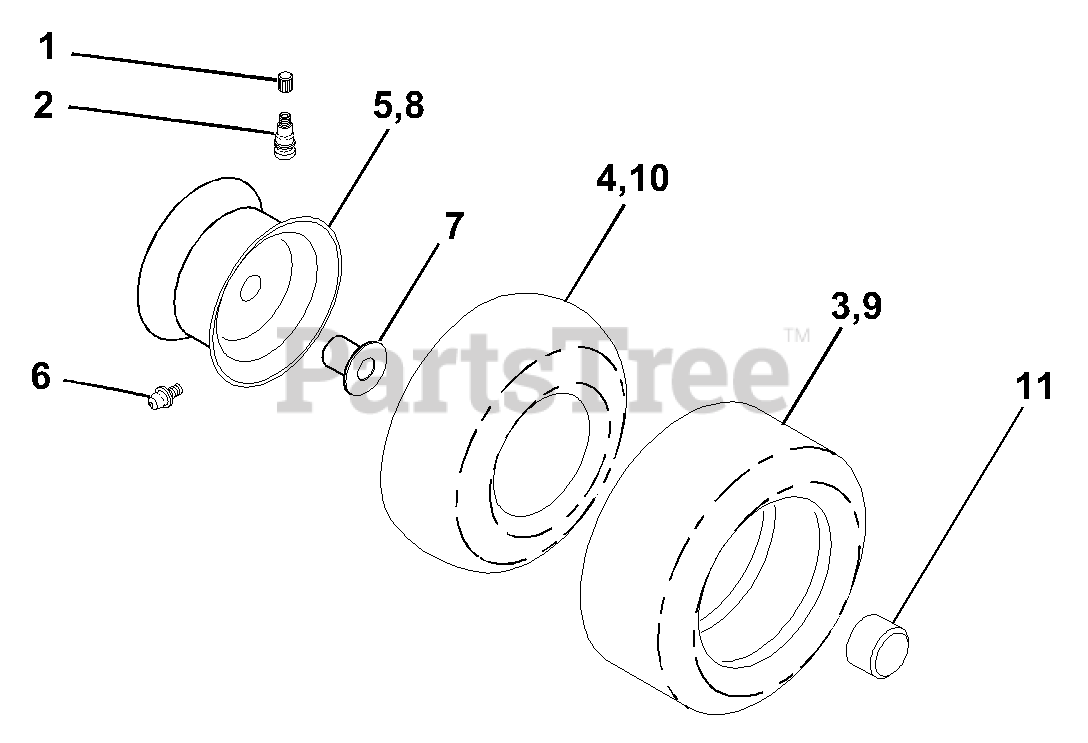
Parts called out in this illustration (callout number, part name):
1	Cap Valve Tire
2	Stem Valve
3	Tire Front
4	Tube Front
5	Rim Asm 8" front
6	Fitting Grease
7	Bearing Flange
8	Rim Asm 12" rear
9	Tire R 23 x 8.5-12 C Service
10	Tube Rear
11	Cap Axle Blk 1 50 X 1 00
